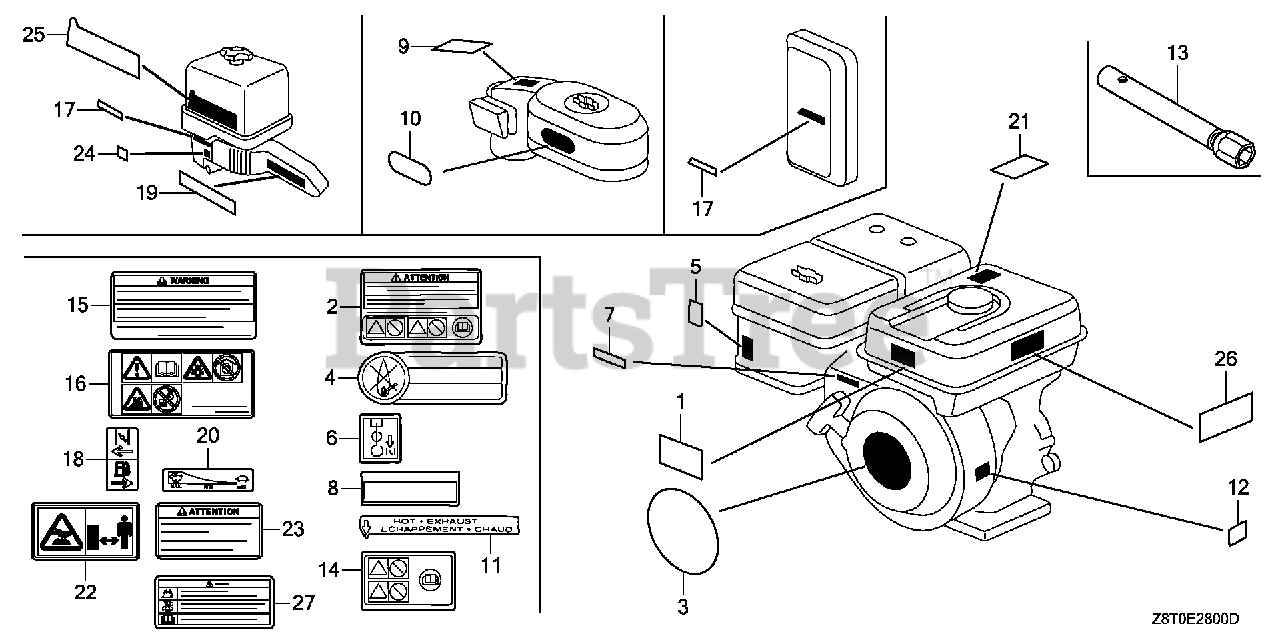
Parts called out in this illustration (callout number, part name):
13	WRENCH, SPARK PLUG
15	MARK, OPERATOR CAUTION (ENGLISH)(MADE IN THAI)
15	MARK, OPERATOR CAUTION (FRENCH)(MADE IN THAI)
16	MARK, OPERATOR CAUTION (PICTOGRAPH)
17	MARK, CHOKE
19	MARK (HONDA)
21	MARK, EX. CAUTION (ENGLISH)
22	MARK, EX. CAUTION (PICTOGRAPH)
23	MARK, EX. CAUTION (FRENCH)
24	MARK, FUEL
25	MARK, SALES POINT
